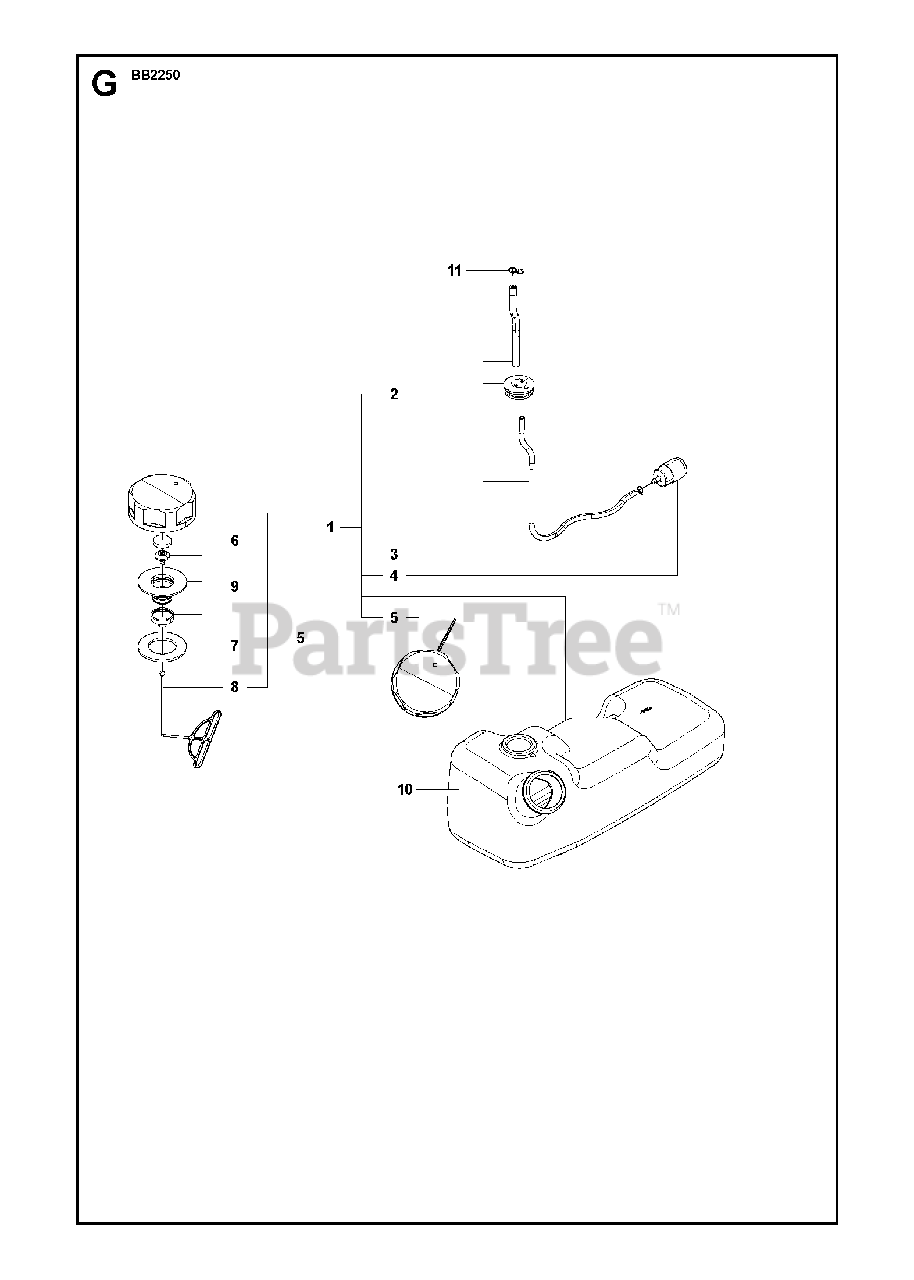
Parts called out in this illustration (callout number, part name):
3	CLIP
4	FILTER
5	CAP A
6	FILTER
7	PACKING
8	STOPPER
9	HOLDER-A
11	CLIP
